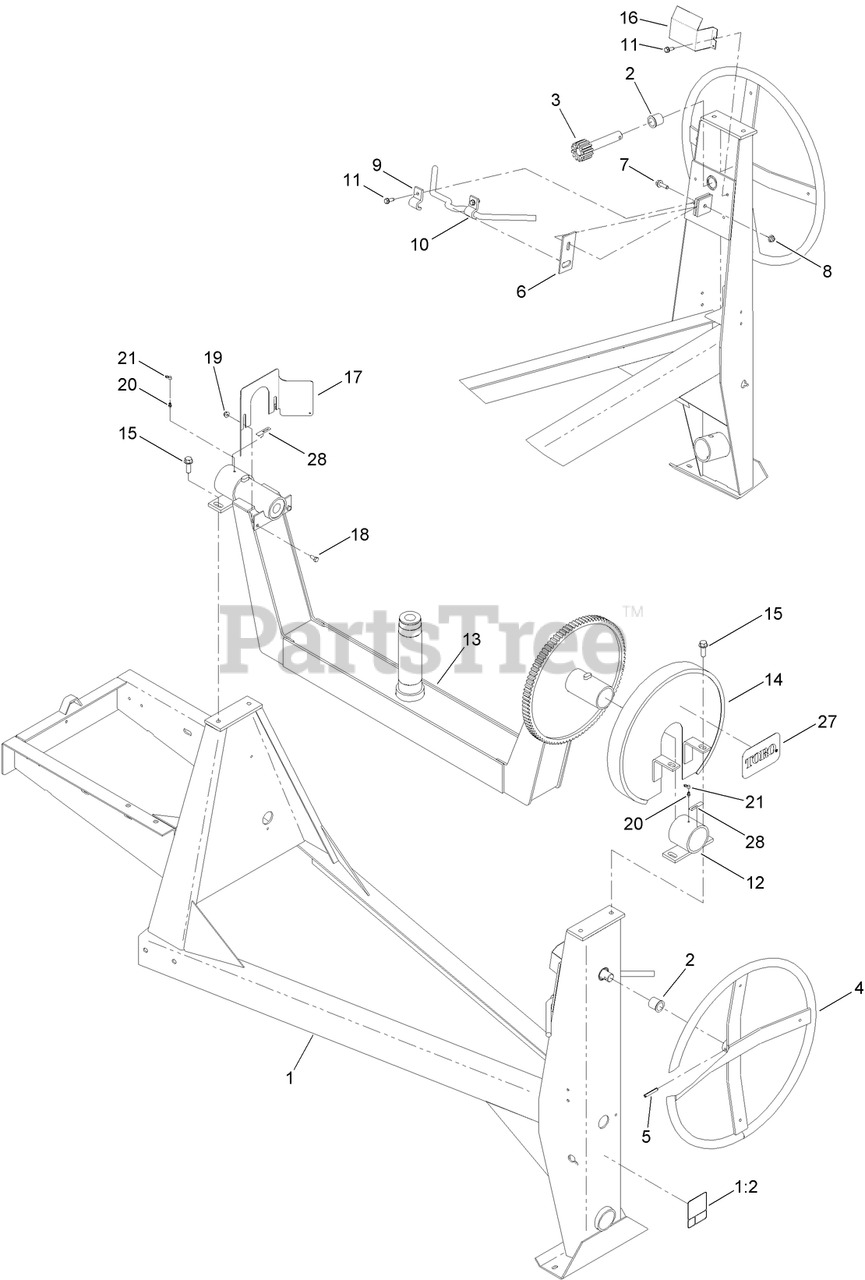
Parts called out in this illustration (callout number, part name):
1	FRAME ASM
1:2	DECAL-SAFETY CHAIN, TOWING
2	BUSHING-NYLON
3	SHAFT-TILT
4	HANDWHEEL
5	PIN-ROLL
6	DOG-BRAKE
7	SCREW-HHF
8	NUT-HF, NI
9	BRACKET-HANDLE
10	HANDLE-BRAKE
11	SCREW-HWHTF
12	TRUNNION
13	YOKE ASM
14	GUARD-BRAKE, UPPER
15	SCREW-HWH
16	GUARD-BRAKE, LOWER
17	GUARD-PINION
18	SCREW-HH
19	NUT-HF, NI
20	FITTING-GREASE
21	CAP-PLUG
27	DECAL
28	DECAL-GREASE
